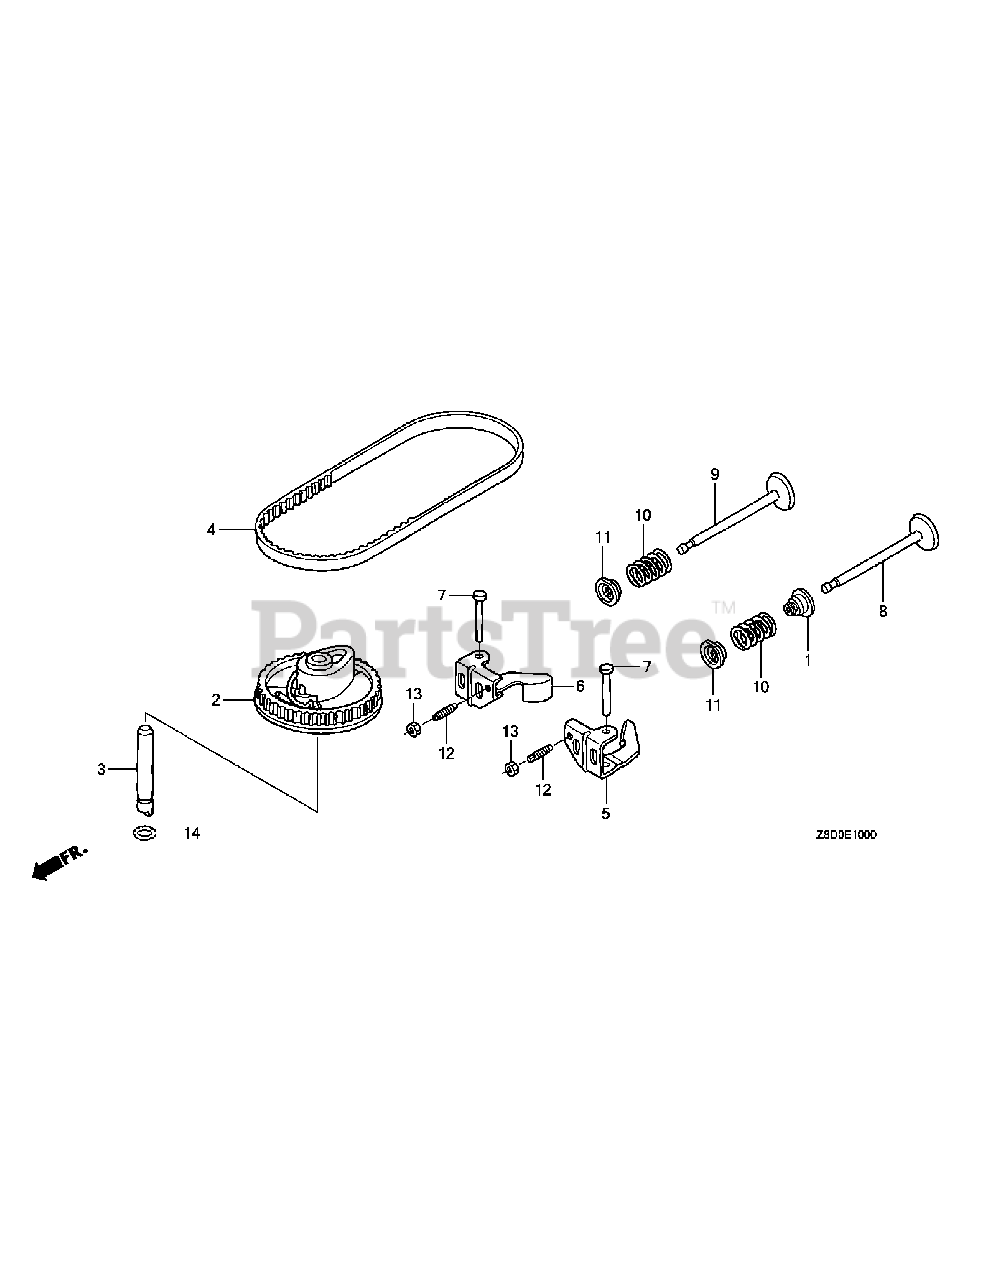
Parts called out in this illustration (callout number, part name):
1	Valve Stem Seal
2	Camshaft Pulley
3	Cam Pulley Shaft
4	Timing Belt, 84HU& G-200
5	Internal Valve Rocker Arm
6	External Valve Rocker Arm
7	Rocker Arm Shaft
8	Internal Valve
9	External Valve
10	Valve Spring
11	Valve Spring Retainer
12	Tappet Adjusting Screw
13	Tappett Adjusting Nut
14	O-Ring, 6.8 x 1.9
